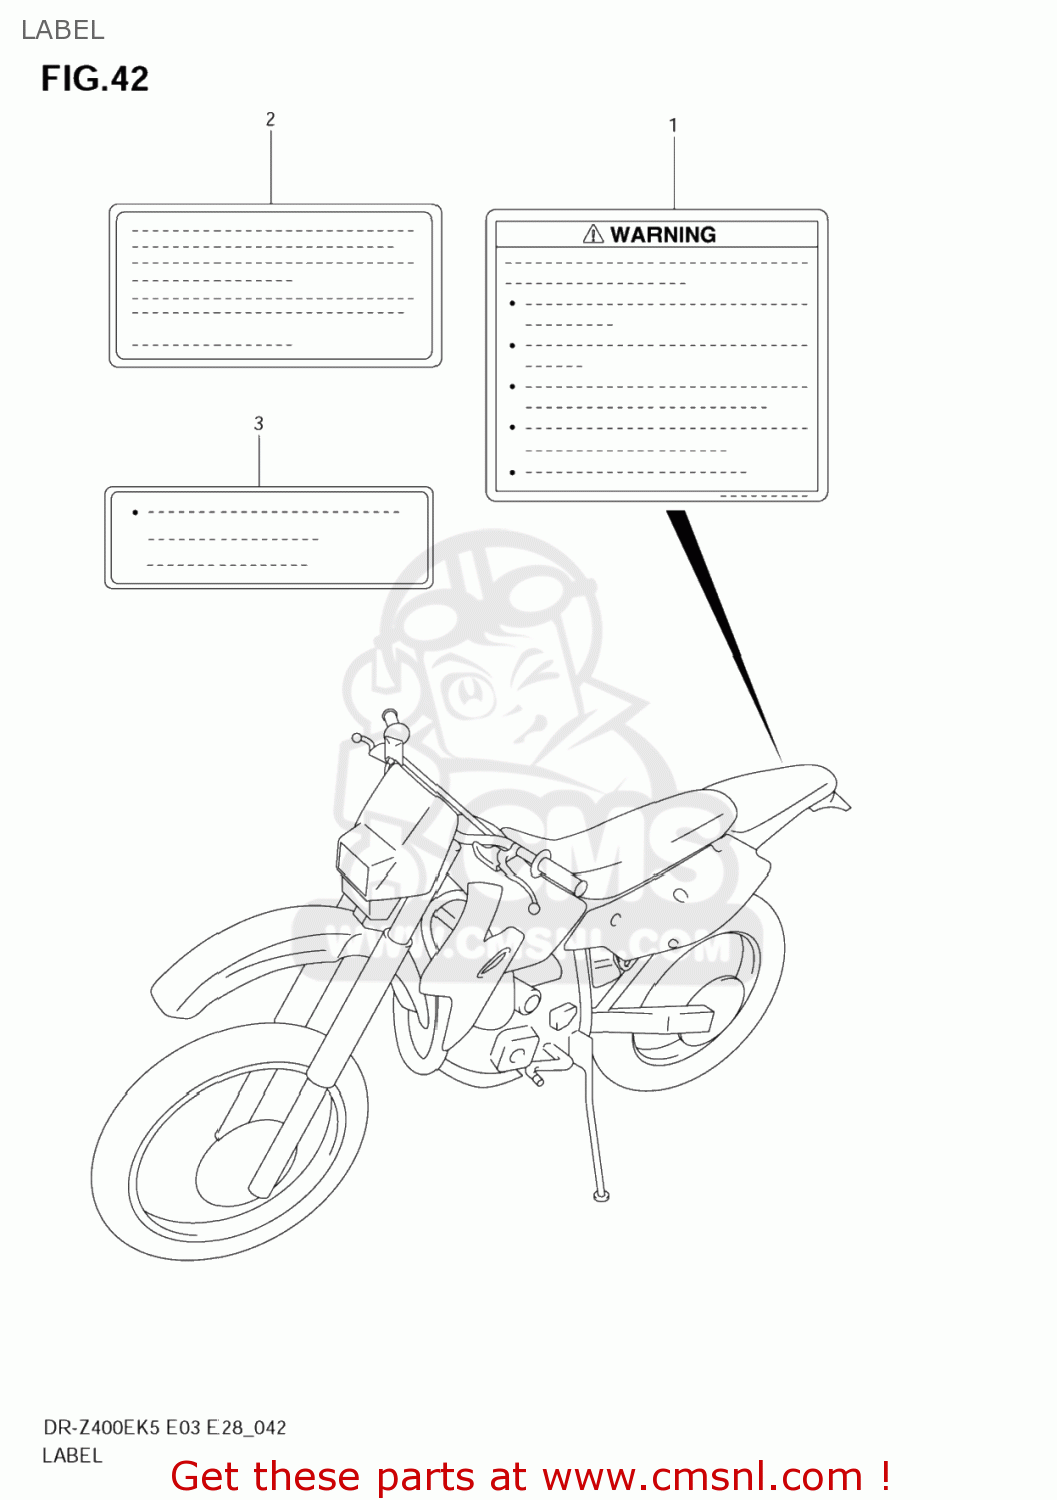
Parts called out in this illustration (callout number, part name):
1	LABEL,GENERAL WARNING
2	LABEL,MANUAL NOTICE
3	LABEL,FUEL INFORMATION
4	MANUAL,OWNER'S
